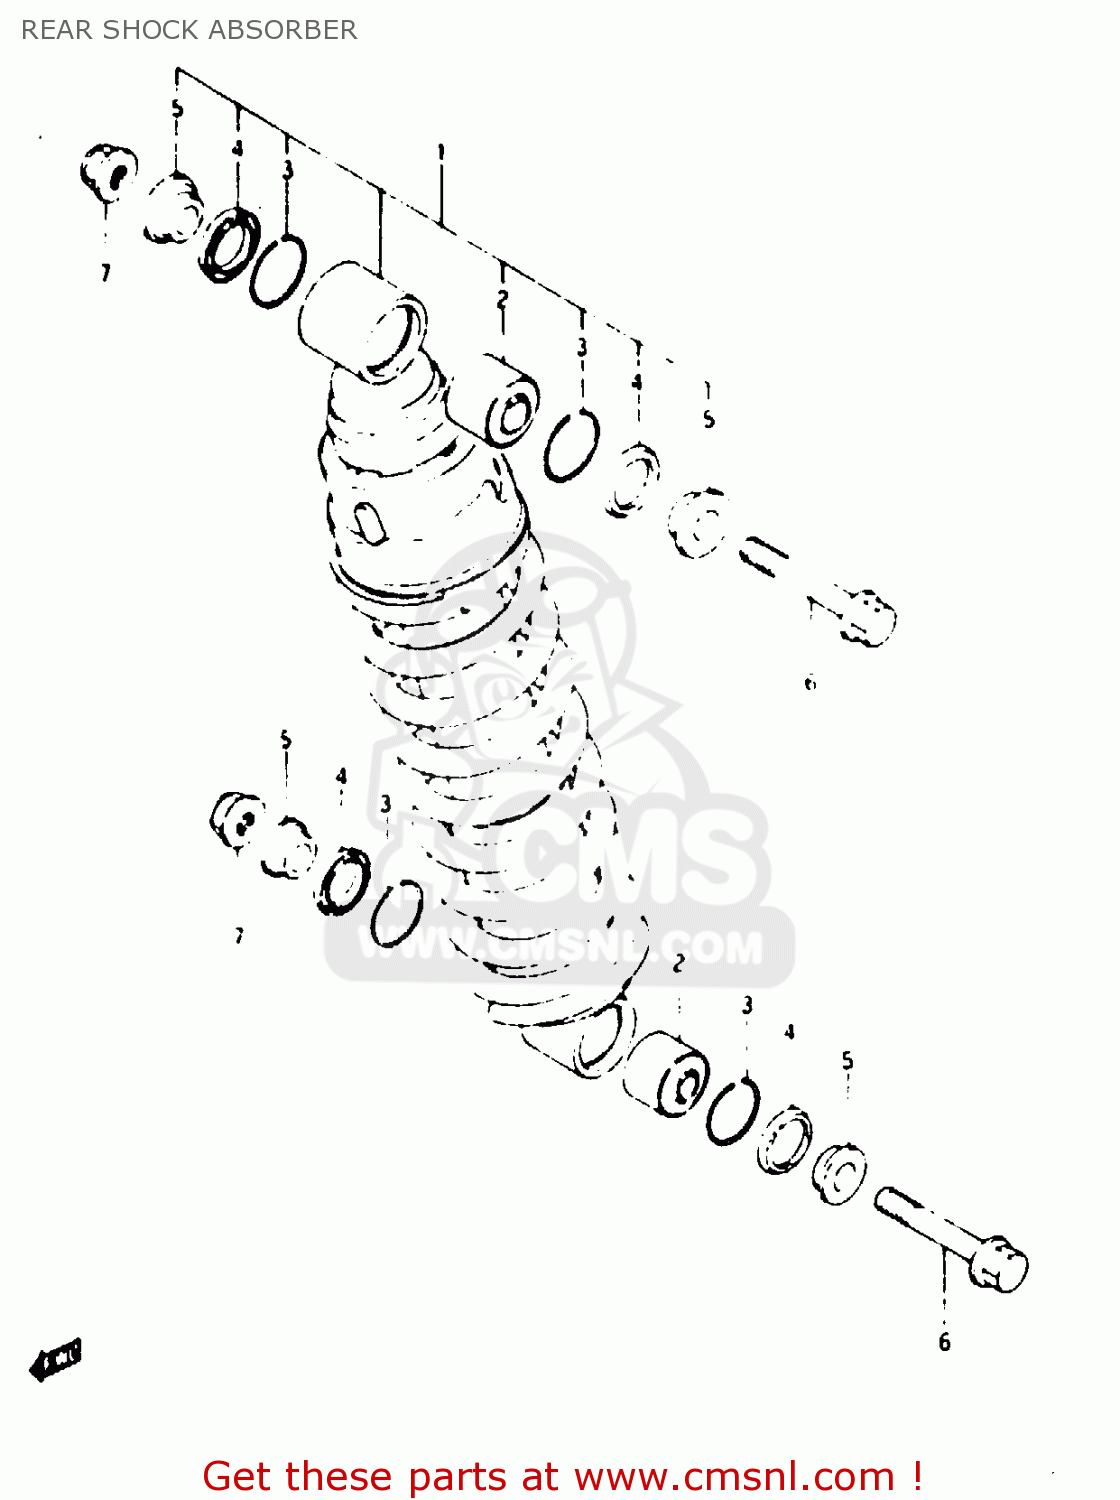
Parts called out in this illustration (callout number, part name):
1	SHOCK ABSORBER, REAR (BLUE)
2	BEARING,REAR SHOCK ABSORBER
3	RING
4	DUST SEAL
5	SPACER
6	BOLT(10X50)
7	NUT
